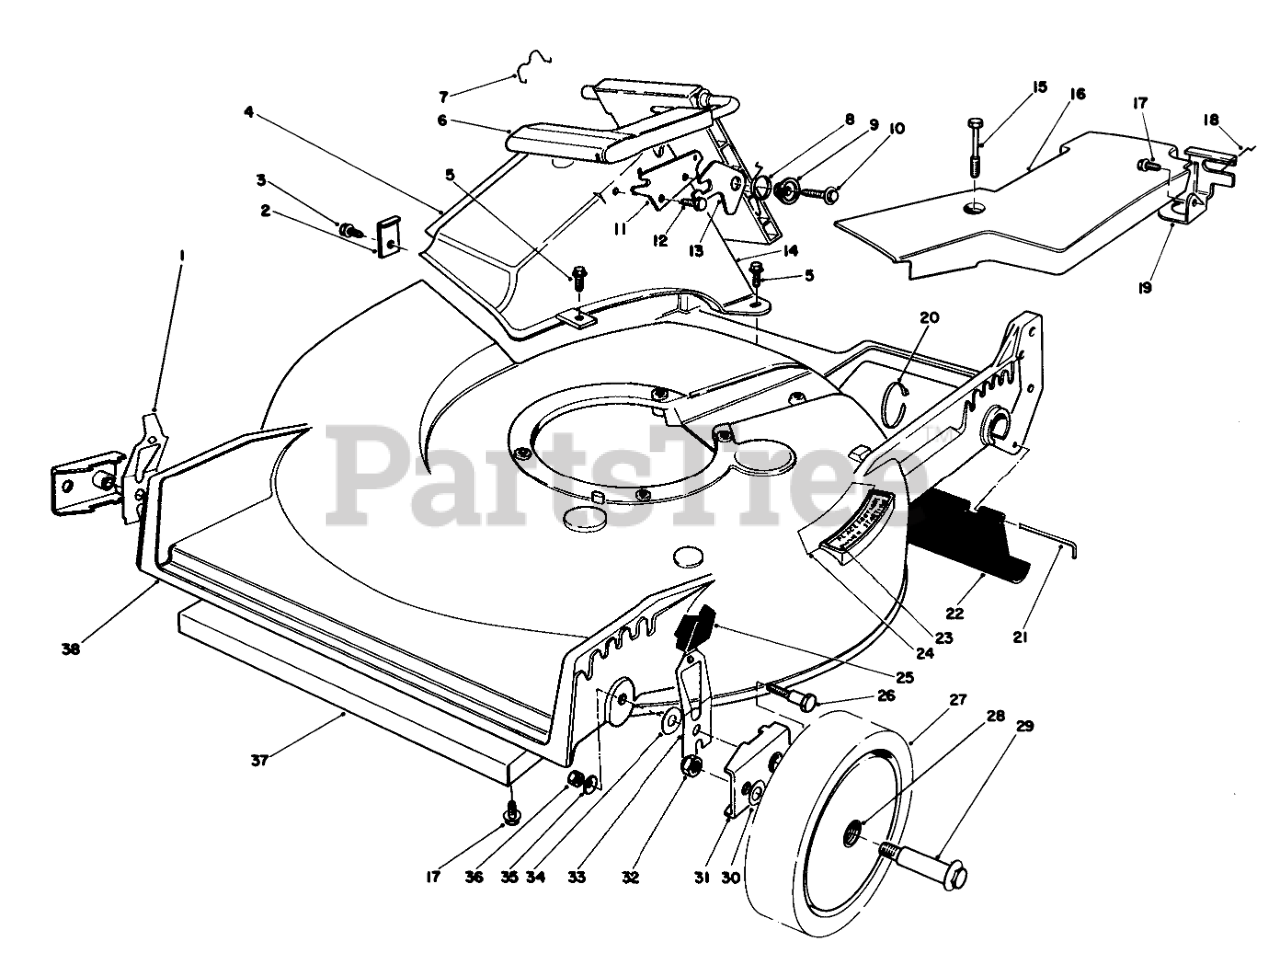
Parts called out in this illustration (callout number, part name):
1	R HP SPRING ARM ASM
2	TUNNEL CLIP
3	SCREW
4	ATTENTION DECAL
5	SCREW-HWH
6	Discharge Door Assembly
7	DOOR RET SPRING
8	TORSION SPRING
9	DOOR SPACER
10	SCREW-HWH
11	DOOR LATCH PLATE
12	SCREW-PLASTITE
13	SAFETY LATCH
14	Tunnel Discharge
15	SCREW-HHFTF
16	Cover-Belt
17	SCREW-HWHTF
18	RETAINER-CABLE
19	Bracket-Traction Adj.
20	TIE-CABLE
21	ROD-SHIELD
22	SHIELD-TRAILING
23	STEP PAD DECAL
24	Decal-Place Foot Here
25	KNOB-ARM
26	PIVOT SCREW
27	Wheel & Tire Assembly (Incl. Ref. #28)
28	BUSHING
29	BOLT-WHEEL
30	WASHER
31	HP PIVOT ARM ASM
32	Nut
33	L. HP SPRING ARM ASM
34	WASHER-PIVOT
35	WASHER-BELLEVILLE
36	NUT-LOCK, NI
37	Shield-front
38	Housing
